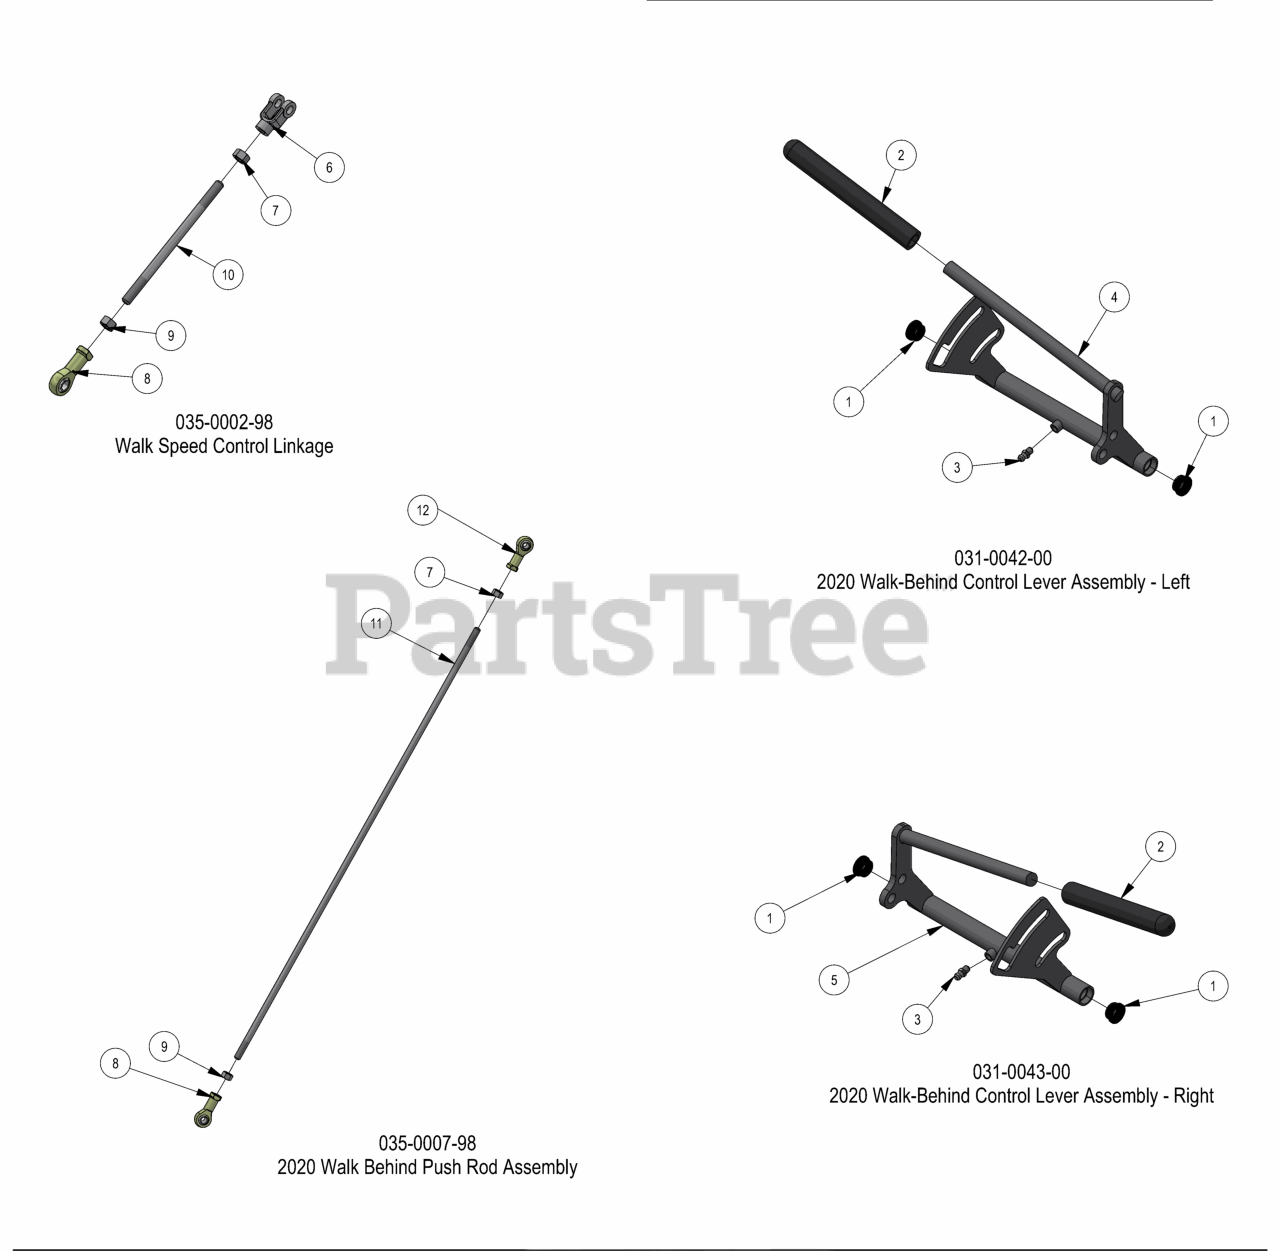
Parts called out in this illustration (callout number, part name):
1	2019 Drive Arm Bushing
2	2019 Stand On Control Grip
3	1/4 DRIVE-TYPE STRAIGHT GREASE FITTING ZINC YELLOW)
4	2020 Walk-Behind Control Lever Weldment - Left
5	2020 Walk-Behind Control Lever Weldment - Right
6	Yoke Left Hand Thread
7	3/8" Left-Handed Fine Threaded Jam Nut
8	Spherical Rod End - Outlaw
9	3/8-24 Hex Nut Zinc
10	Walk Speed Control Rod
11	2020 Walk Behind Push Rod (Rod Only)
12	Swivel Heim left handed thread
